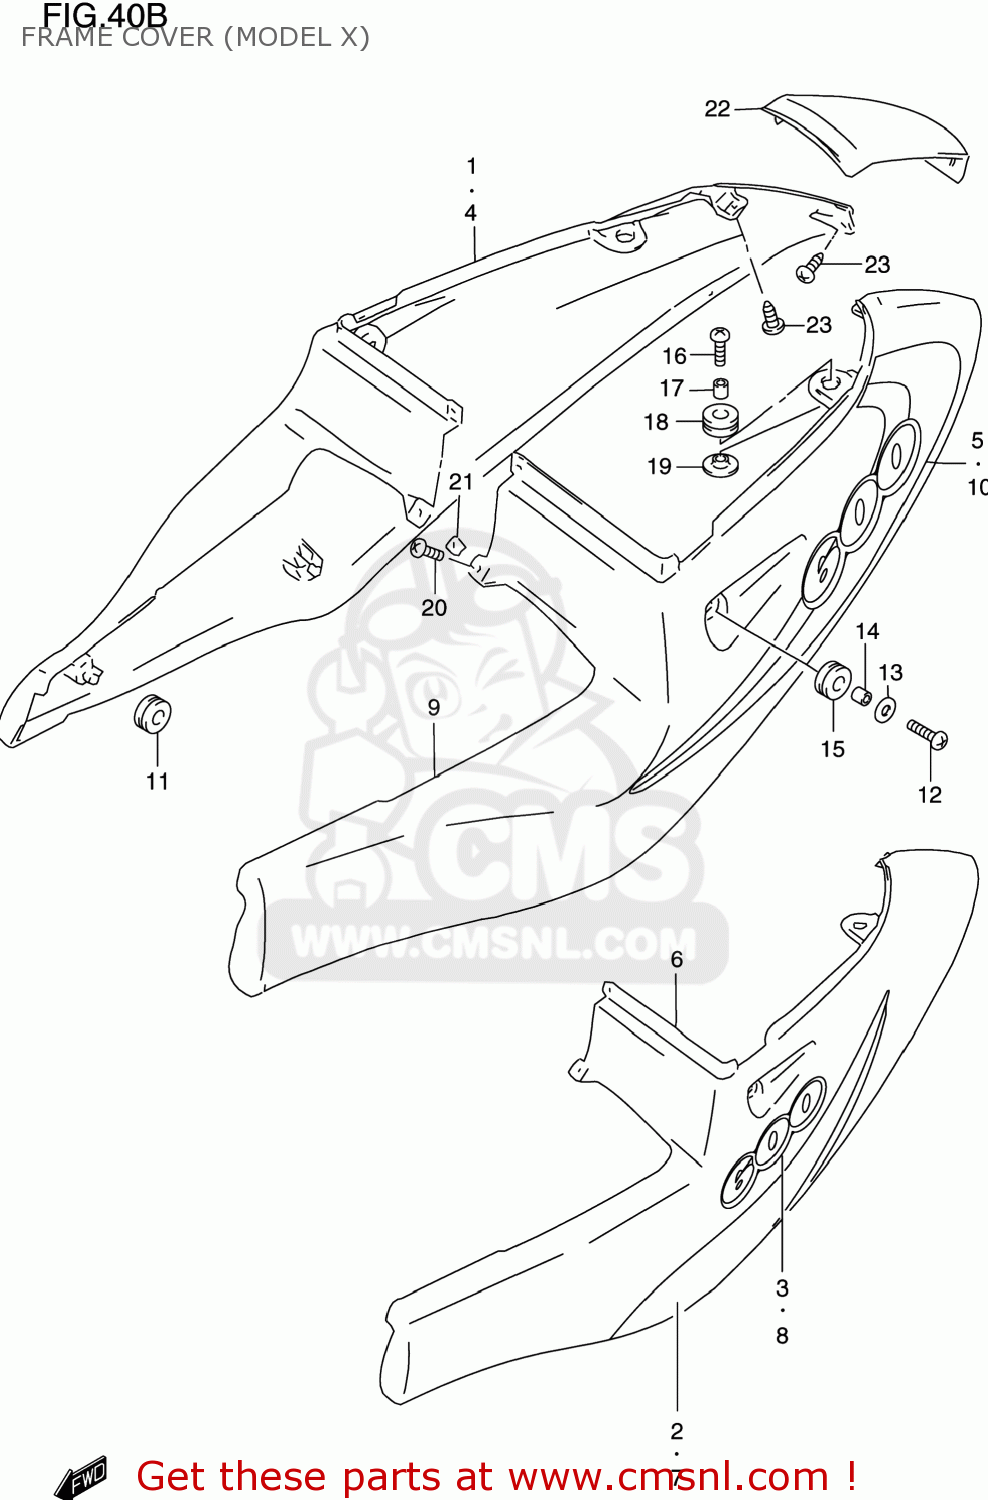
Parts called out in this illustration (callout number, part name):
1	COVER,FRAME,R(WHITE)
2	TAPE,FRAME COVER,R
3	EMBLEM,FRAME COVER
4	COVER,FRAME,R(BLACK)
5	EMBLEM,FRAME COVER STRIPE,R
6	COVER,FRAME,L(WHITE)
7	TAPE,FRAME COVER,L
8	EMBLEM,FRAME COVER
9	COVER,FRAME,L(BLACK)
10	EMBLEM,FRAME COVER STRIPE,L
11	CUSHION
12	SCREW(6X20)
13	WASHER(6.5X22X1.6)
14	SPACER(6.5X9X6.7)
15	CUSHION
16	SCREW(6X25)
17	SPACER(6.5X10X9.4)
18	CUSHION,TAIL COVER UPR
19	CUSHION,FRAME COVER LWR
20	SCREW
21	NUT
22	COVER,FRAME CTR
23	SCREW
